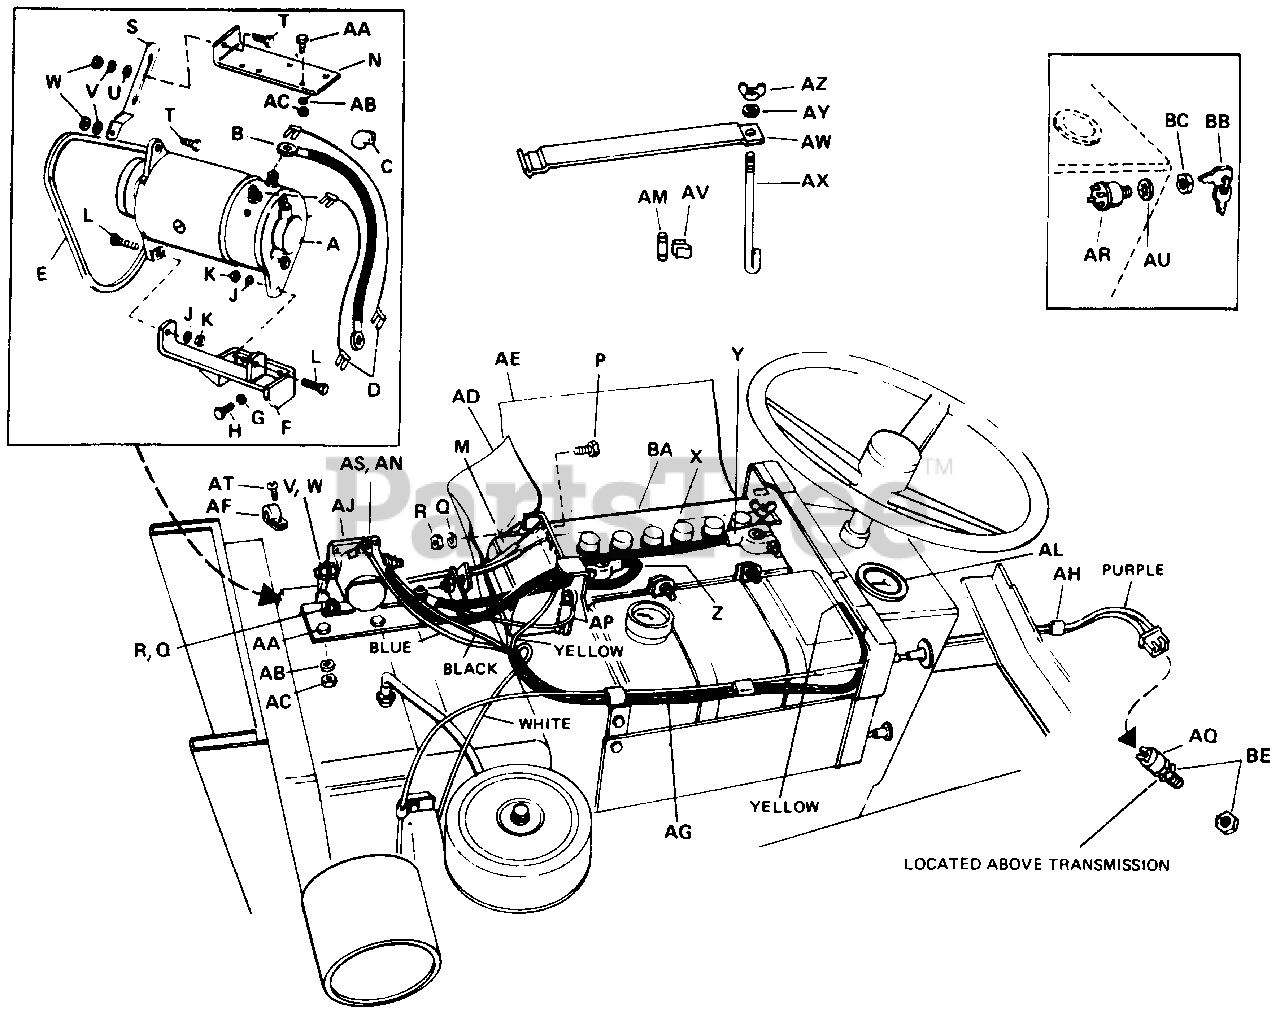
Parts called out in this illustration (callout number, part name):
A	Motor-Generator
B	Generator Start Cable
C	Terminal Cover
D	Reg. Gen. Wire
E	V-BELT, 39.12"
F	Support Assembly
G	Lock Washer, 5/16"
H	Hex. Capscrew, 5/16-18 x 3/4" lg.
J	Lock Washer, 5/16"
K	Full Hex. Nut, 5/16"-18
L	Hex. Capscrew, 5/16"-18 x 1-1/4"
M	Voltage Regulator
P	Hex. Capscrew, 1/4-20 x 3/4" lg.
Q	Lock Washer, 1/4"
R	Full Hex.Nut, 1/4"-20
S	Belt Tightener
T	Hex. Capscrew, 5/16 18 x 3/4" lg.
U	Plain Washer, 5/16"
V	Lock Washer, 5/16"
W	Full Hex. Nut, 5/16"-18
Y	Cable (Battery to Solenoid)
Z	Cable (Battery to Ground)
AA	Hex.Capscrew, 1/4-20 x 5/8" lg.
AB	Lock Washer, 1/4"
AC	Full Hex. Nut, 1/4"-20
AD	Battery Insulation
AE	Fuel Tank Insulation
AF	Wire Clamp (Generator Cable)
AG	Harness Assembly
AH	Speed Clip
AK	Full Hex. Nut, 1/4"-20
AL	Ammeter
AM	Fuse, 20 AMP
AN	Full Hex. Nut, 10-32
AP	Wire (Ground to Ground)
AQ	Safety Switch
AR	Starter Switch w/Keys
AS	Lock Washer, ext. No. 10
AT	Rd. Hd. Screw 10-24 x 1/2"
AU	Lock Washer Int. 9/16"
AV	Clip Fuse
AW	Battery Bracket
AY	Lock Washer, 1/4"
BA	Film (SIMPLICITY)
BC	Hex Nut-Special
BD	Switch Support
BE	Nut
